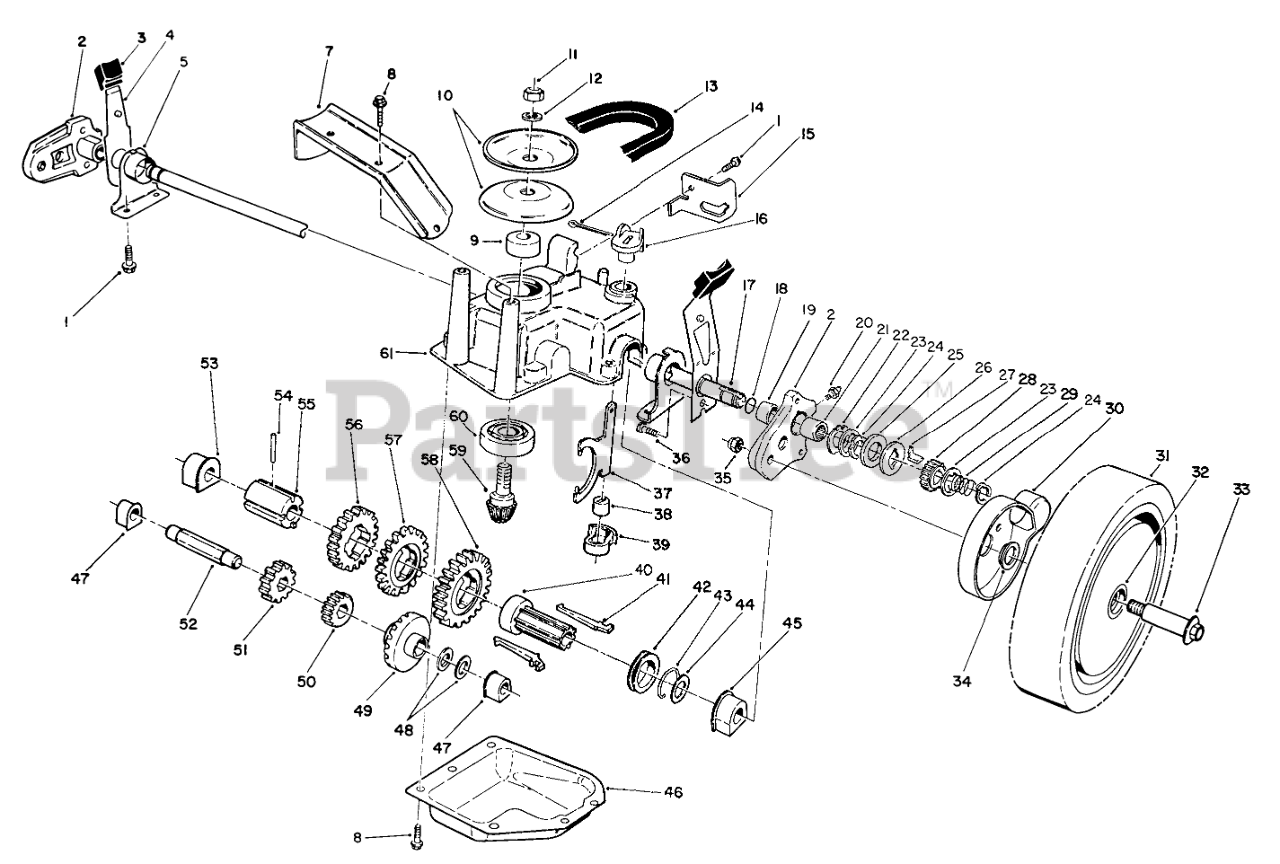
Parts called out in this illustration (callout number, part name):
1	SCREW-HWHTF
2	Pivot Arm Assembly (Incl. Ref. #19-21)
3	KNOB-ARM
4	SPRING ARM ASM
5	CAP-END
7	Bracket-BeltGuide
8	SCREW-HWHTF
9	SPACER
10	Pulley Half
11	NUT-HEX
12	WASHER-FLAT
13	V-BELT
14	PIN-COTTER
15	RETAINER-CABLE
16	LEVER-SHIFT
17	SHAFT-OUTPUT
18	O-RING
19	BUSHING
20	FITTING-GREASE
21	BEARING-ROLLER
22	WASHER-ARM, PIVOT
23	WASHER-THRUST, KEYED
24	RING-CLIP, LOCKING
25	RING-FRICTION
26	WASHER-CLUTCH
27	KEY-ROCKING, LH
28	GEAR-PINION
29	SPRING-COMPRESSION
30	COVER-WHEEL
31	Wheel Tire & Gear Assy. (Incl. Ref. #32)
32	BUSHING
33	WHEEL BOLT
34	SPACER-COVER, WHEEL
35	NUT-LOCK
36	SCREW-HSH, THREAD FORMING
37	YOKE-SHIFT
38	BUSHING-YOKE
39	RETAINER-FORK, SHIFT
40	SLEEVE-KEY, SHIFT
41	KEY-SHIFT
42	COLLAR-SHIFT
43	CLIP-SPRING
44	WASHER-PLAIN
45	BUSHING-OUTPUT
46	Cover-Gearcase
47	BUSHING
48	WASHER-THRUST
49	Gear-Bevel
50	PINION-20T
51	PINION-25T
52	SHAFT-INTERMEDIATE
53	BUSHING
54	PIN-SPRING
55	SLEEVE-GEAR
56	GEAR-39T
57	GEAR-44T
58	GEAR-49T
59	Gear-Pinion
60	BEARING-BALL
61	CASE-GEAR, UPPER
